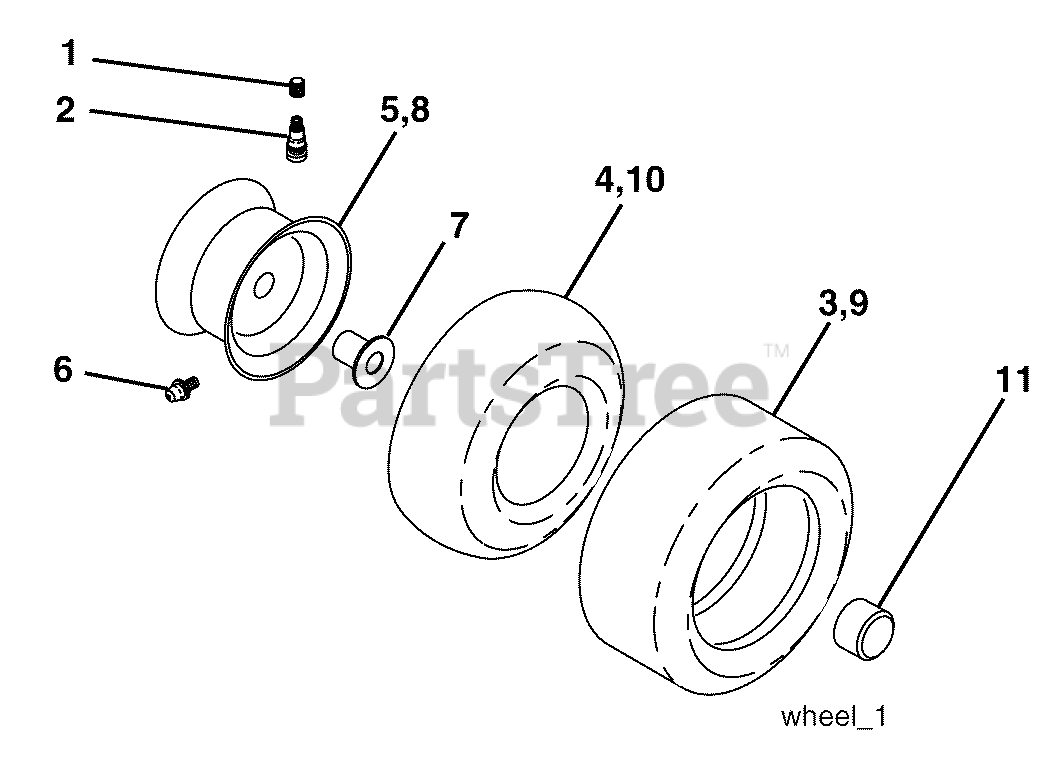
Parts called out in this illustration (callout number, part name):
1	Cap Valve Tire
2	Stem Valve
3	Tire F Ts 15 x 6 0 - 6 Service
4	Tube Front
5	Rim Asm 6"front Silver Service
6	Fitting Grease
7	Bearing Flange
8	Rim Asm 8"rear Silver Service
9	Tire R Ts 20 x 8-8 C Service
10	Tube Rear
11	Cap Axle Blk 1 50 x 1 00
